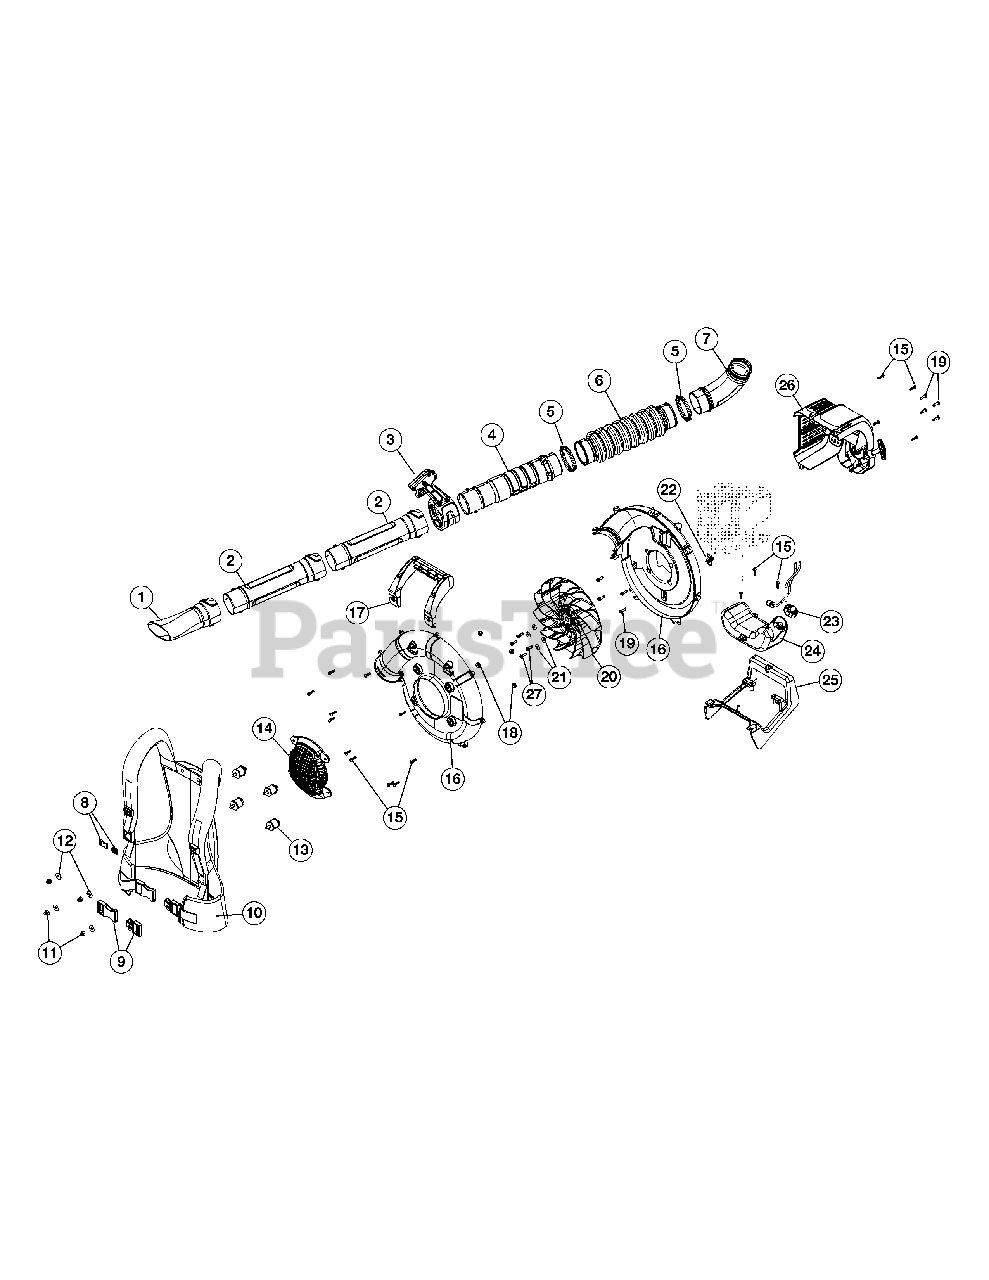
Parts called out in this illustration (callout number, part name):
2	Lower Blower Tube
3	Throttle Grip Assembly
4	Upper Blower Tube
7	Elbow Tube
8	Upper Support Clip
9	Lower Support Clip
10	Support System (includes 8 & 9)
11	Nut
13	Insulator Mount
14	Intake Cover
16	Impeller Housing Assembly
18	Nut
19	Screw
20	Impeller (includes 19)
22	Throttle Retaining Clip
24	Fuel Tank Assembly (includes 23)
26	Engine Cover Assembly
